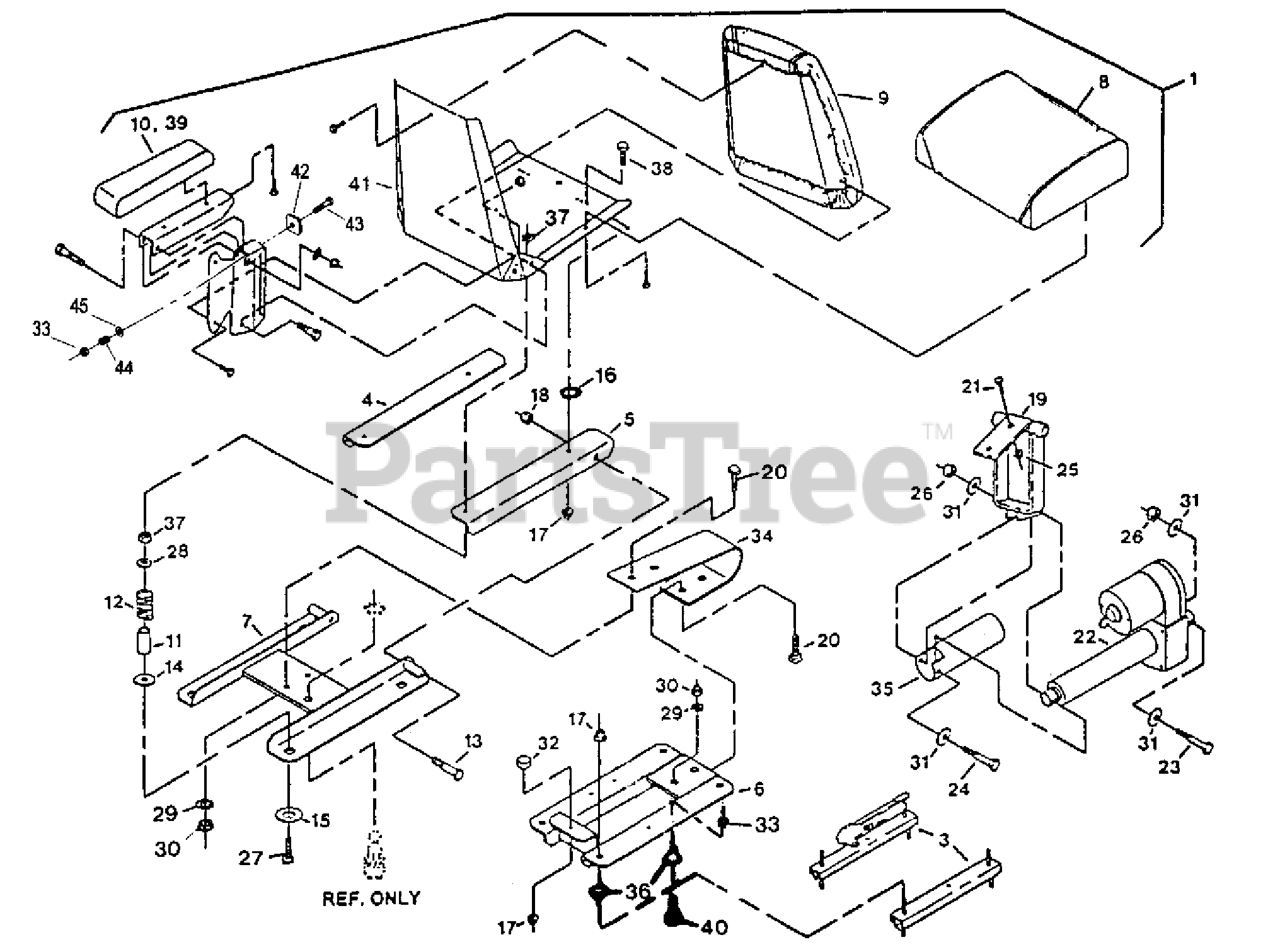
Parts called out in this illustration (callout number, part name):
4	RAIL,SEAT LH
5	RAIL,SEAT RH
10	CUSHION,ARMREST RH
11	BUSHING,SPRING GUIDE
12	SPRING-INDICATOR, REVERSE
13	SCREW-HH
14	SCREW-HH
16	WASHER-FLAT
18	NUT-LOCK, NI
20	SCREW-HH
21	SCREW-HH
23	SCREW-HH
24	SCREW-HH
25	NUT-HHF, WHIZ
26	NUT-LOCK
27	BOLT,TAP HH
28	WASHER-FLAT
29	WASHER-LOCK
30	NUT-HH
31	WASHER-FLAT
32	BUMPER-RUBBER
33	NUT-LOCK, NI
35	GUARD,ACTUATOR
36	SPACER-TRACK
37	NUT-HEX
39	CUSHION,ARMREST LH
40	SCREW-PPH
41	FRAME-SEAT
42	TAB,ARMREST ADJUSTMENT
43	SCREW-HH
44	SPRING-TANK, FUEL
45	WASHER-PLAIN
